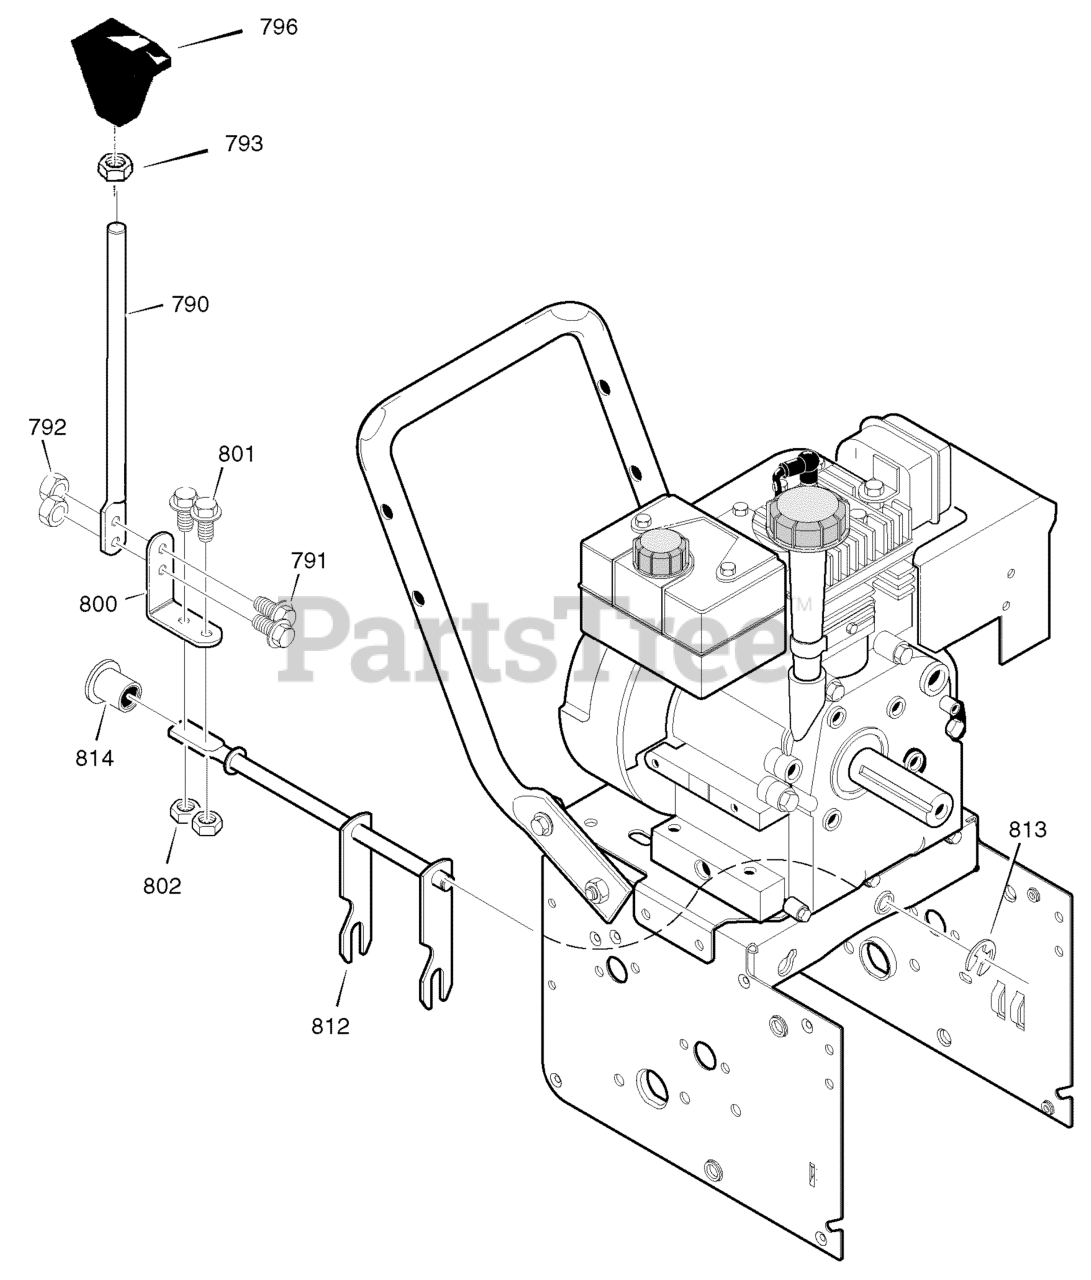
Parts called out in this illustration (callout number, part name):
790	ROD, SHIFT
791	SCREW, 1/4-20X.75
792	NUT, 1/4-20
793	NUT, JAM
800	LEVER, SPRING
801	SCREW, 1/4-20X.75
802	NUT, 1/4-20
812	ROD ASSY., SPEED SELECT
813	RETAINER, RING
814	BEARING, FLANGED
